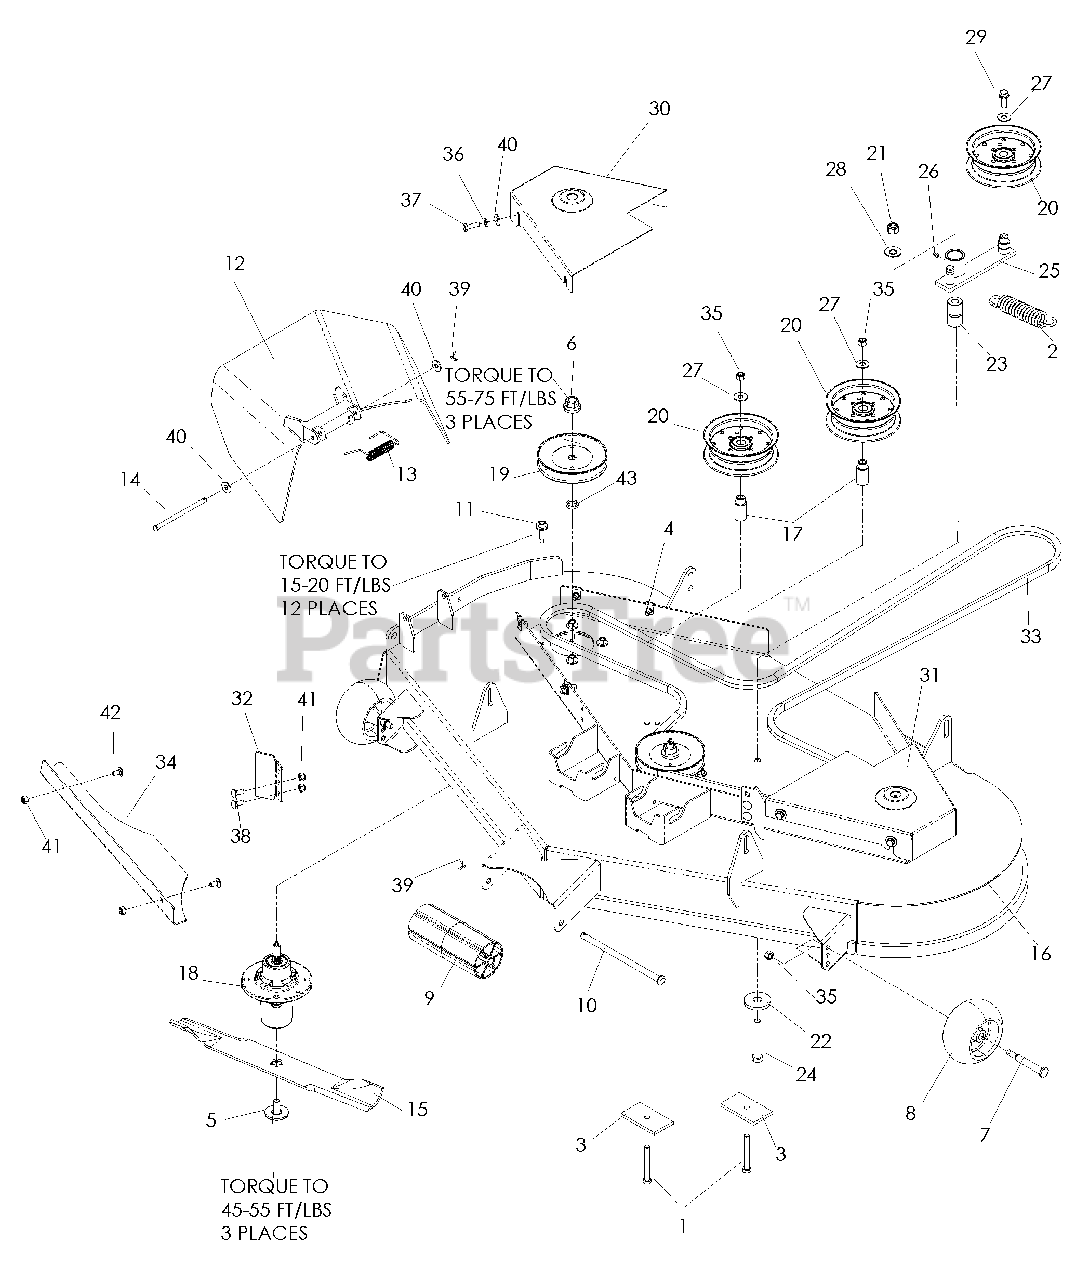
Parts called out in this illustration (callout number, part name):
1	HCS 3/8-16
2	SPRING, EXTENSION
3	PAD
4	NUT 5/16-18 RETAINER-U
5	BOLT 7/16 SPEC
6	NUT 9/16 CENTERLOCK
7	BOLT, SHOULDER
8	WHEEL, GAUGE
9	ROLLER, NOSE
10	ROD, ROLLER, NARROW
11	SCREW 5/16-18 x 1 3/8 WSH HD
12	DISCHARGE CHUTE
13	SPRING, TORSION
14	PIN-CLEVIS 5/16 DIA x 5.19
16	DECK W/DECALS
17	IDLER BUSHING
19	PULLEY
20	IDLER PULLEY, NYLON
21	NUT 1/2-13 NYLOC
22	WASHER .65, SUPPORT
23	BUSHING-PIVOT
24	HCS 1/2-13 x 3 1/4
26	ZERK, STRAIGHT 1/4-28
27	WASHER 3/8
28	WASHER 1/2
29	HCS 3/8-16 x 1 WHIZLK
30	BELT SHIELD, RIGHT
31	BELT SHIELD, LEFT
34	CONFINEMENT PLATE
35	NUT 3/8-16 NYLOC
36	WASHER 5/16
37	HCS 5/16-18 x 1
38	RHSNB 5/16-18 x 3/4
39	PIN COTTER 1/8 x 3/4
40	WASHER 5/16
41	NUT 5/16-18 NYLOC
42	RHSNB 5/16-18 x 5/8
43	WASHER .675 SPACER
